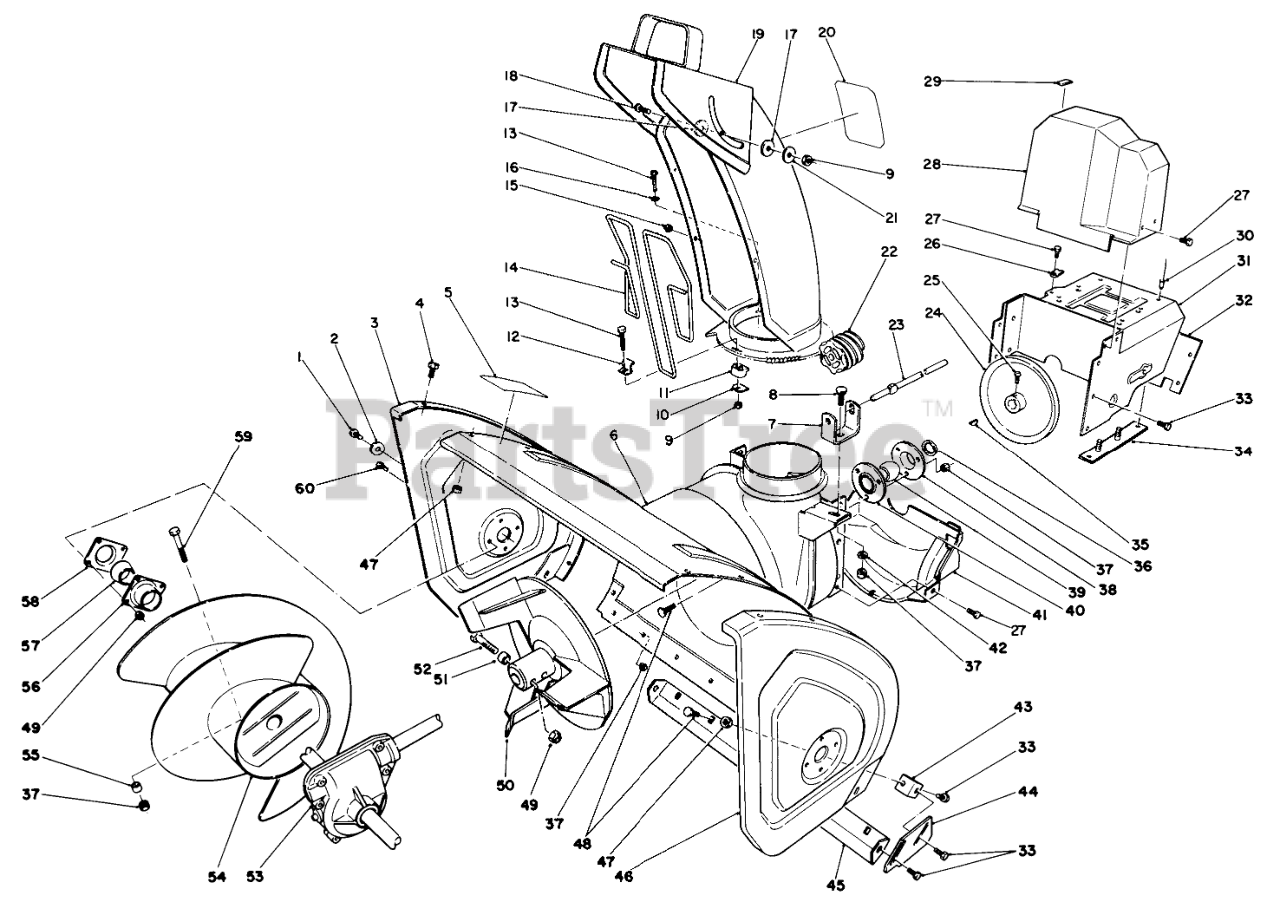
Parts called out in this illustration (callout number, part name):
1	SCREW-HH
2	WASHER
3	PLATE-SIDE, RH
4	SCREW-HHF
5	DECAL-WARNING, AUGER
6	Housing-24 Inch
7	BRACKET-WORM, CHUTE
8	BOLT-CARR
9	NUT-LOCK, NI
10	PLATE-RETAINER, CHUTE
11	RETAINER-CHUTE
12	CLIP-GUARD, CHUTE
13	SCREW-HSH
14	GUARD-CHUTE
15	NUT-PUSH
16	WASHER-FLAT
17	WASHER-PLASTIC
19	Assembly
20	Decal-Danger
21	WASHER-FLAT
22	GEAR-WORM
23	ROD-CHUTE, LOWER
24	PULLEY-IMPELLER
25	SCREW-SET, SQH
26	RETAINER-CABLE
27	SCREW-HWH
28	COVER-BELT, UPPER
29	COVER-CABLE
30	RIVET-POP
31	Frame-Engine
32	Cover-Frame, Engine
33	SCREW-HHF
34	PLATE ASM FRM LH 8 MITS
35	KEY-WOODRUFF
36	WASHER-THRUST
37	NUT-LOCK, NI
38	Flange-Bearing (Rear)
39	BEARING-BALL
40	Flange-Bearing (Front)
41	Cover-Belt (Lower)
42	WASHER-PLAIN
43	Bracket-Skid
44	Plate-Skid LH
45	Blade-Scraper
46	Plate-Side LH
47	NUT-LOCK, NI
48	SCREW-CARR
49	NUT-LOCK, NI
50	Impeller
51	SPACER
52	SCREW-HHF
53	Auger Gearbox ASM
54	Auger-RH
55	SPACER-HUB, AUGER
56	BEARING-FLANGE, FRONT
57	BEARING
58	BEARING-FLANGE, REAR
59	Auger Bolt
60	SCREW-HH
